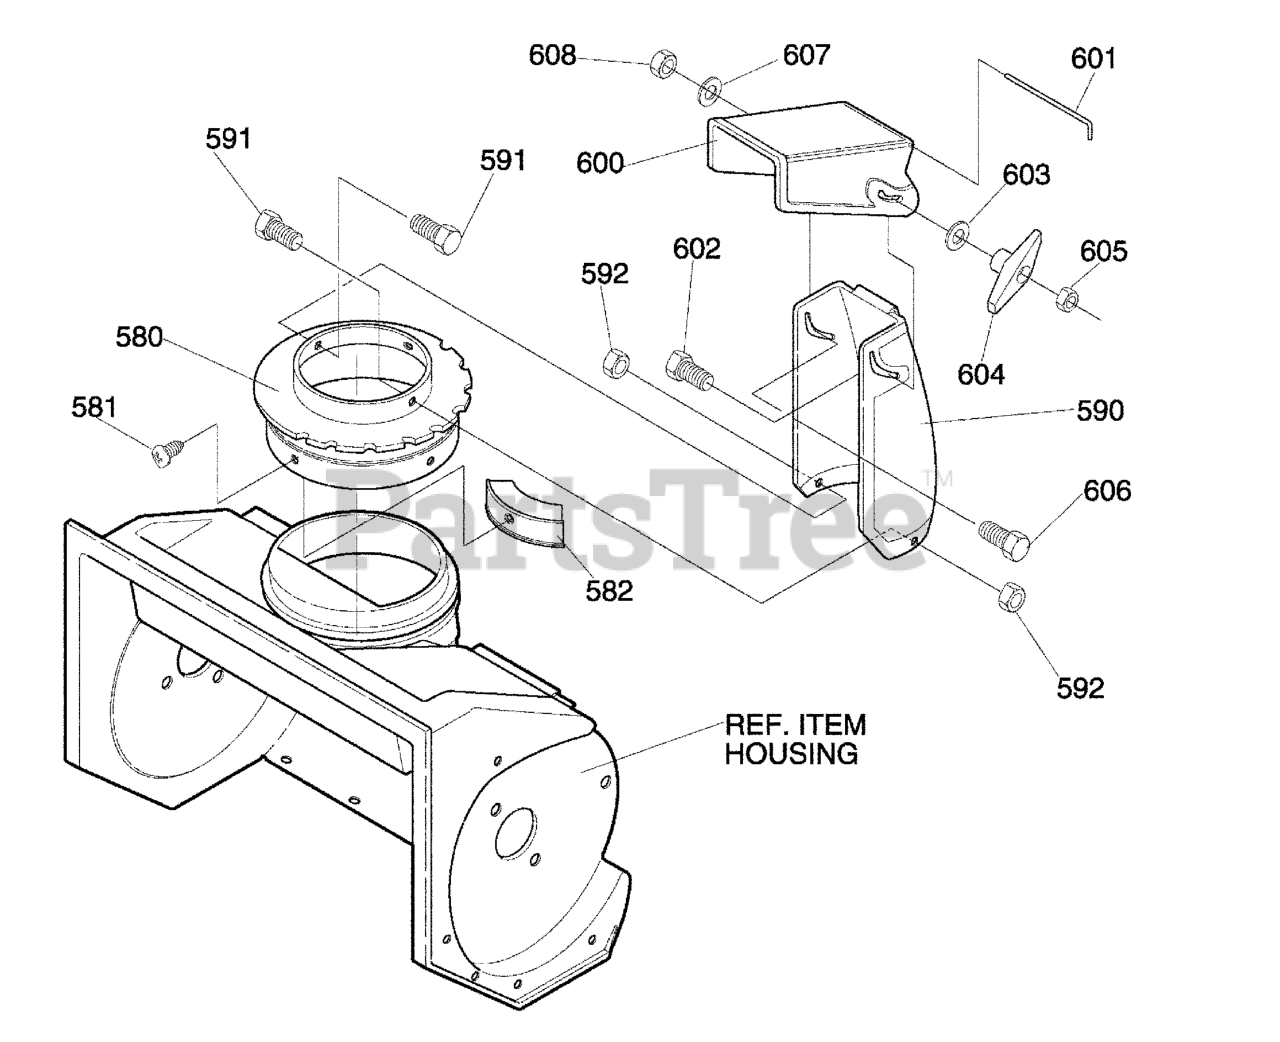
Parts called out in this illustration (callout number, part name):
580	RING, CHUTE
581	SCREW, #10X.50
582	GUIDE, CHUTE
590	CHUTE, LOWER
591	SCREW 1/4-20X.50
592	NUT, 1/4-2
600	CHUTE, UPPER
601	WIRE, HINGE
602	BOLT, 5/16-18X1.25
603	WASHER, FLAT
604	KNOB, T
605	NUT, 5/16-18
606	SCREW, 5/16-18 x 0.75
607	WASHER, FLAT
608	NUT, 5/16-18
